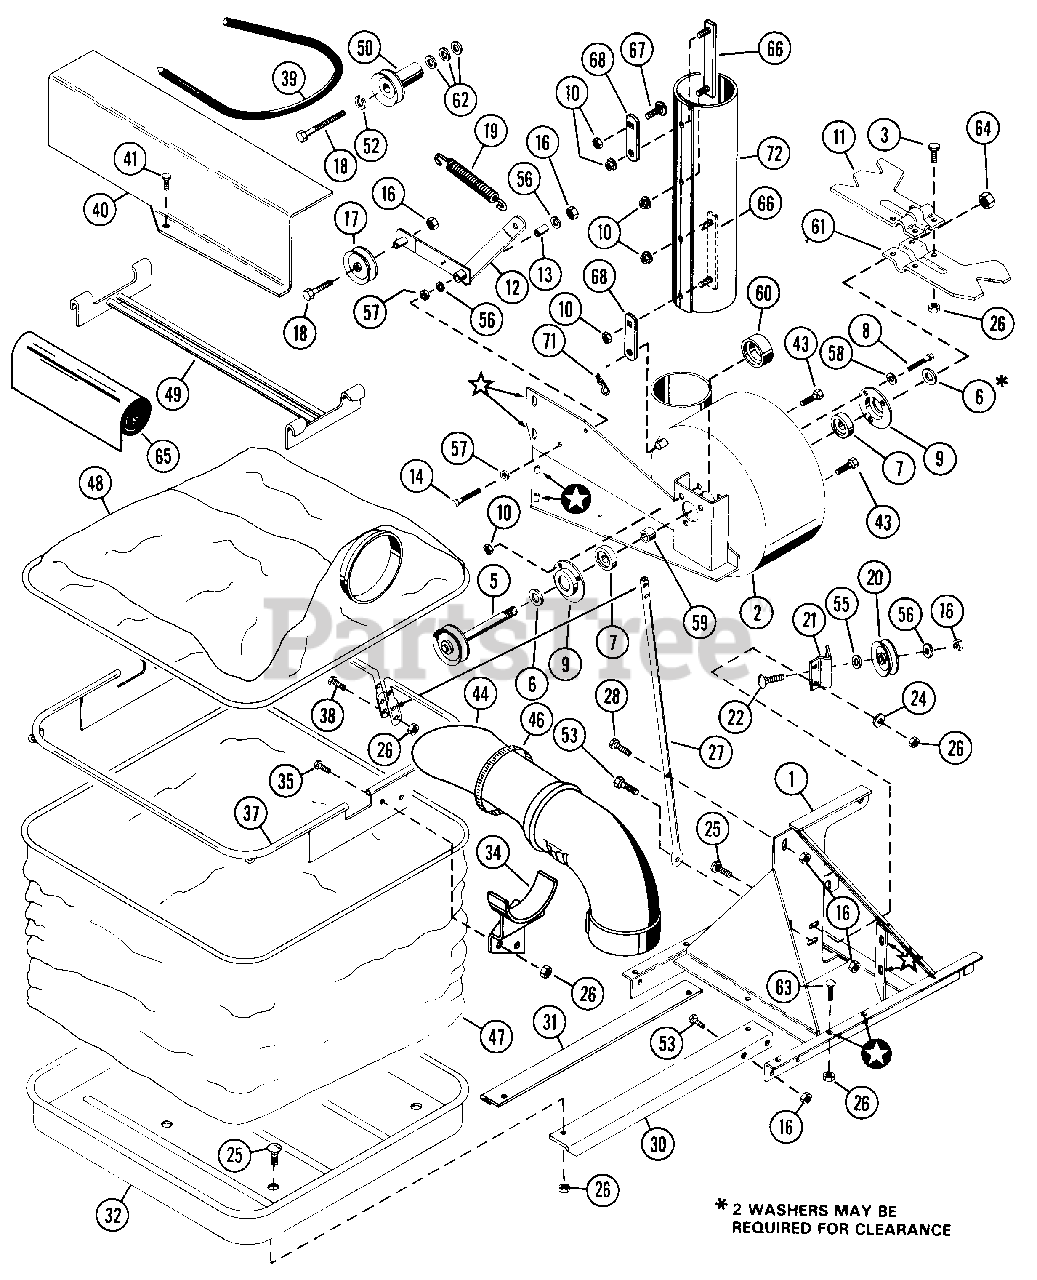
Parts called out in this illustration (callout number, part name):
1	FRAME TRAILER
2	FAN HOUSING
3	BOLT, HEX 5/16-18X.625
5	WELDMENT, SPINDLE
6	WASHER, FLAT 1.0X1.5X.125
7	BEARING, BALL
8	BOLT, HEX 1/4-20X2.00
9	BEARING, FLANGE
10	NUT, LOCK 1/4-20
11	BLADE, FAN
12	ARM, IDLER
13	SPACER BUSHING
14	BOLT, HEX 3/8-16X2.75
16	NUT, LOCK 3/8-16
17	IDLER
18	BOLT, HEX 3/8-16X2.50
19	SPRING, EXTENSION 6" FREE LENGTH
20	IDLER, .375X4
21	IDLER MOUNT
22	BOLT, 3/8-16X1.25 RD HD SQ NK
24	WASHER, FLAT .312X.734X.065
25	BOLT, CARRIAGE 5/16-18X.75
26	NUT, LOCK 5/16-18
27	SUPPORT TUBE
28	BOLT, HEX 3/8-16X2.25
30	RIGHT TRAY SUPPORT
31	LEFT TRAY SUPPORT
32	BAG TRAY
34	BRACKET, ELBOW SUPPORT
35	BOLT, HEX 5/16-18X.75
37	BAG SUPPORT WELDMENT
38	BOLT, HEX 5/16-18X2.50
39	V-BELT
40	BELT SHIELD
41	SCREW, TAPTITE 1/4-20X.375
43	BOLT, HEX 5/16-18X.50
44	ELBOW, UPPER
46	CLAMP, HOSE
48	COVER
49	CENTER BAG SUPPORT
50	PULLEY, PTO
52	WASHER, LOCK 3/8 REG.
53	BOLT, HEX 3/8-16X1.00
55	WASHER, .515/.535X.810X.033
56	WASHER, FLAT .406X.812X.065
57	WASHER, FLAT .39X.87X.18
58	WASHER, FLAT .263/.273X.562X.046
59	SPACER
60	HOUSING
61	BLADE, FAN
62	SHIM
63	BOLT, 5/16-18X.626 RD HD SQ NK
64	NUT, LOCK 1-14 JAM
65	BAGS,(10) ROLL
66	CLIP
67	BOLT, CARRIAGE 1/4-20X.50
68	STRAP
71	HAIR PIN, INTERNAL 3/32
72	UPPER TUBE BLANK
NS	DECAL, AMERICA
NS	WARNING DECAL
